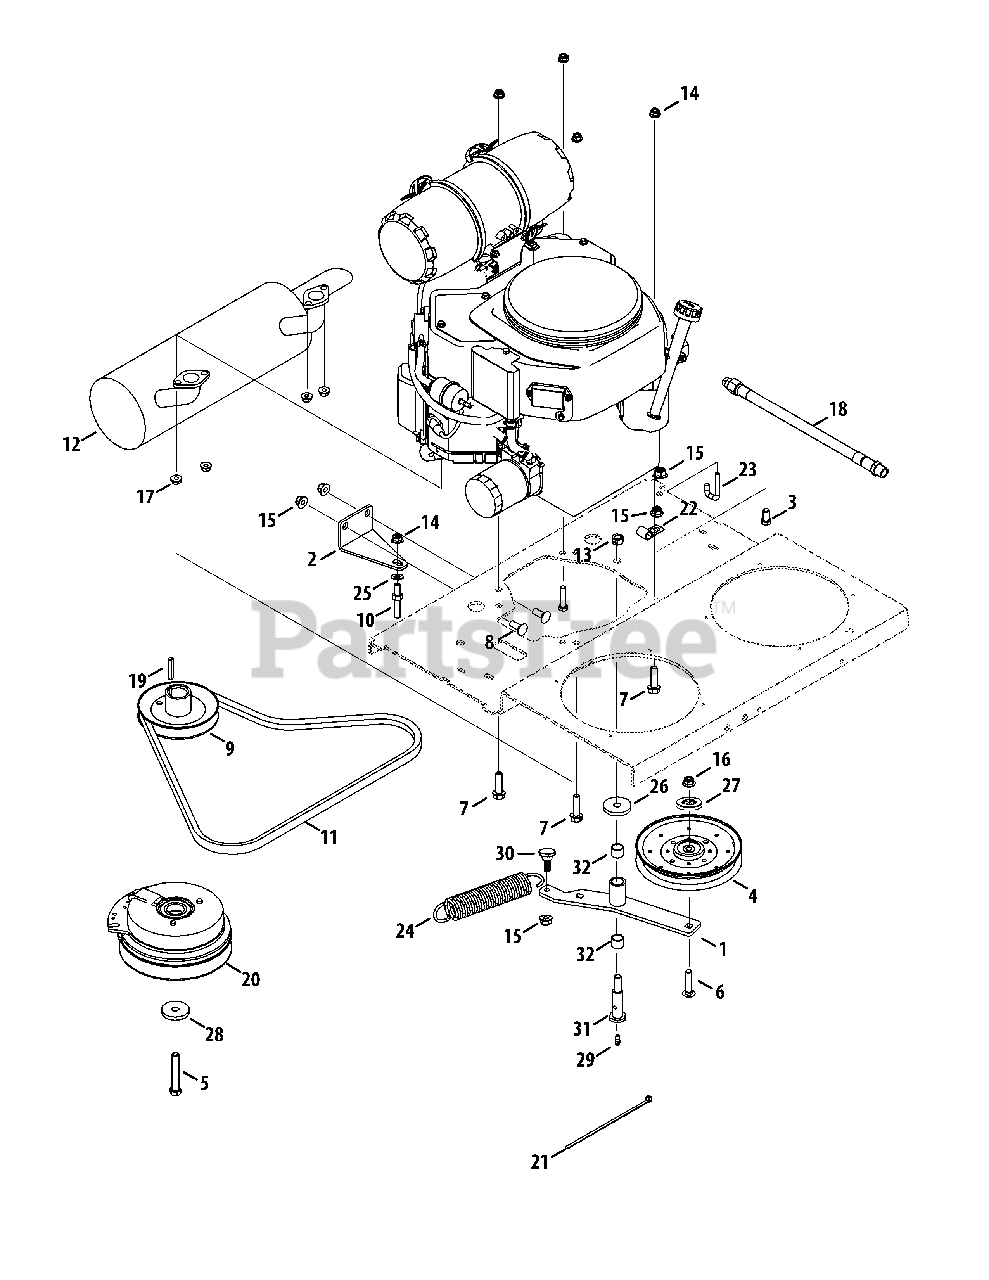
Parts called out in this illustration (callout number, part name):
1	Idler Bracket
2	Clutch Retainer Bracket
3	Hex Cap Screw, 3/8-16 x .75
4	Idler Pulley
5	Hex Cap Screw, 7/16-20 x 2.75
6	Carriage Bolt, 3/8-16 x 1.00
7	Hex Flange Screw, 3/8-16
8	Carriage Bolt, 3/8-16 x 1.00
9	Drive Pulley
10	Stud, Pivot Ball Joint
13	Nut, 7/16-14, Hexlock
14	Nut, 5/16-18, Flangelock
15	Nut, 3/8-16, Flangelock
16	Nut, 3/8-16, Flangelock
17	Nut, M8-1.25, Hexlock
18	Oil Drain Hose
19	Key, 1/4 x 1.50
20	Electric PTO Clutch
21	Cable Tie
22	Clip, .407 x 1.80
23	Transmission Spring Hook
24	Extension Spring, 1.5 x 7.5
25	Washer, .344 x .688 x .065
26	Washer, .471 x 1.50 x .225
27	Pulley Cap
28	Washer, .471 x 1.50 x .225
29	Grease Fitting
30	Shoulder Screw, .625 x .302, 3/8-16
31	Shoulder Bolt, .625 x 1.947, 7/16-14
32	Bearing, .638 x .753 x .615
